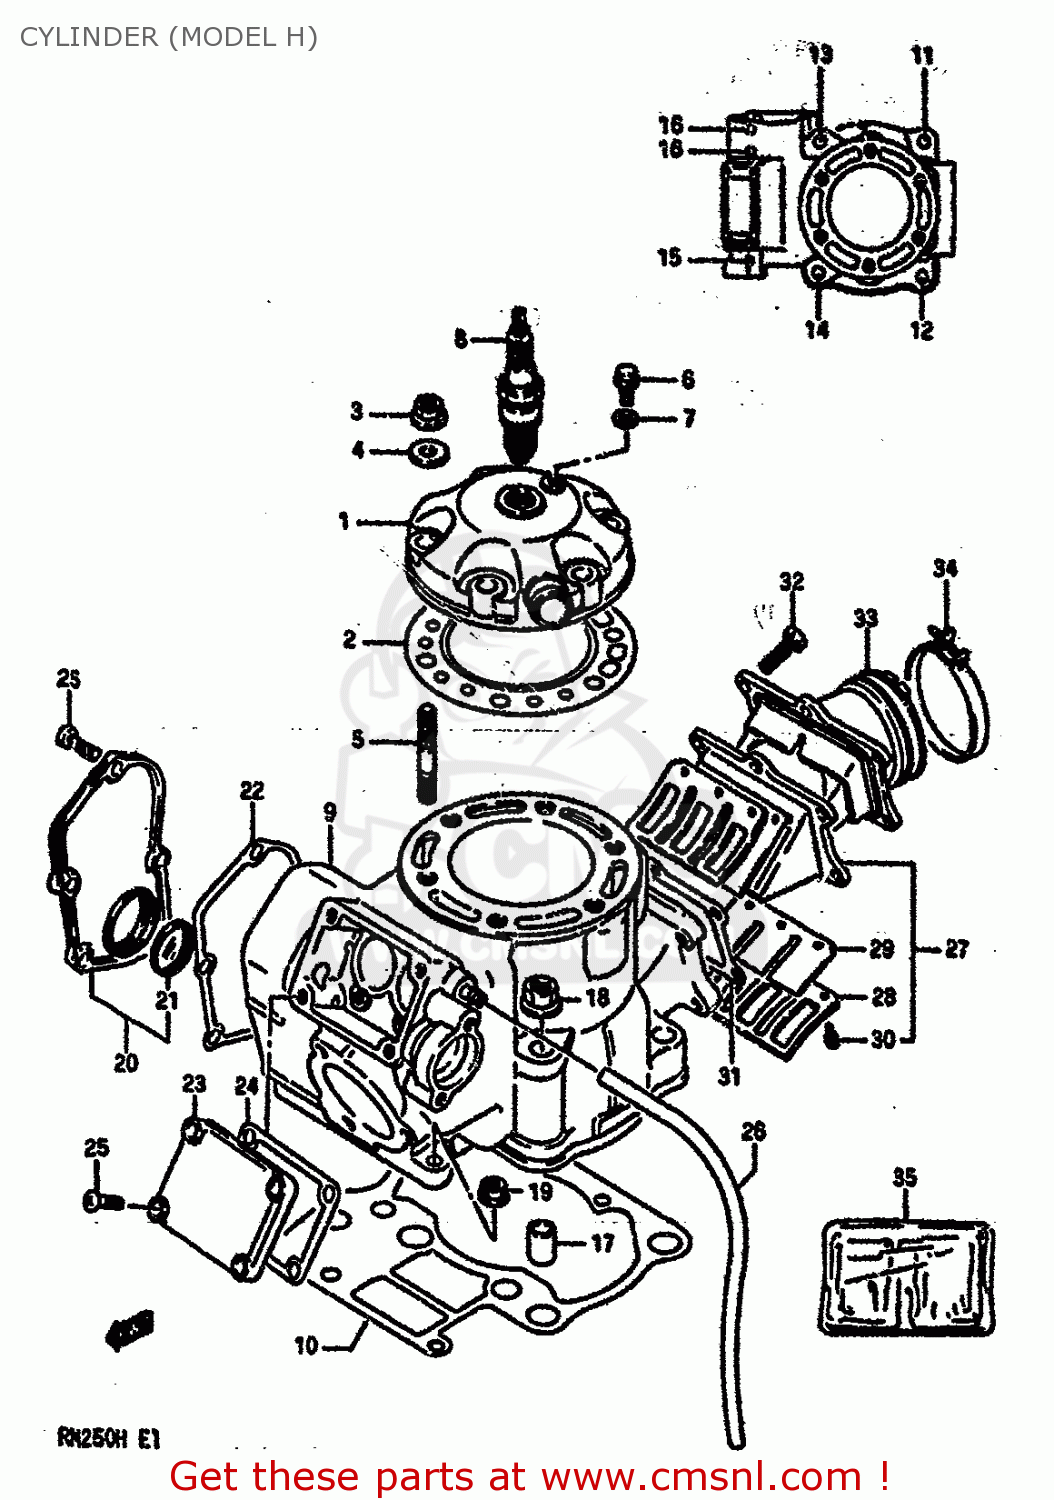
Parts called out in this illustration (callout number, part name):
1	HEAD,CYLINDER
2	GASKET,CYLINDER HEAD (MCA)
3	NUT
4	WASHER
5	BOLT,STUD
6	UNION
7	GASKET(6.2X11X1).2 (NAS)
8	PLUG,SPARK(NGK B-8EN)
9	CYLINDER
10	GASKET,CYLINDER (MCA)
11	STUD BOLT (L:40)
12	STUD BOLT (10X50)
13	STUD
14	STUD BOLT (10X90)
15	STUD 6X25
16	STUD BOLT
17	PIN
18	NUT
19	NUT
20	COVER COMP,CYLINDER
21	LENS,CYLINDER COVER
22	GASKET,CYLINDER COVER (MCA)
23	COVER,CYLINDER NO.2
24	GASKET,CYLINDER COVER NO.2 (MCA)
25	SCREW
26	HOSE
27	VALVE ASSEMBLY,REED
28	STOPPER,REED VALVE
29	VALVE,REED
30	SCREW,REED VALVE
31	GASKET,REED VALVE (MCA)
32	BOLT
33	PIPE,INTAKE
34	CLAMP
35	GASKET SET (MCA)
